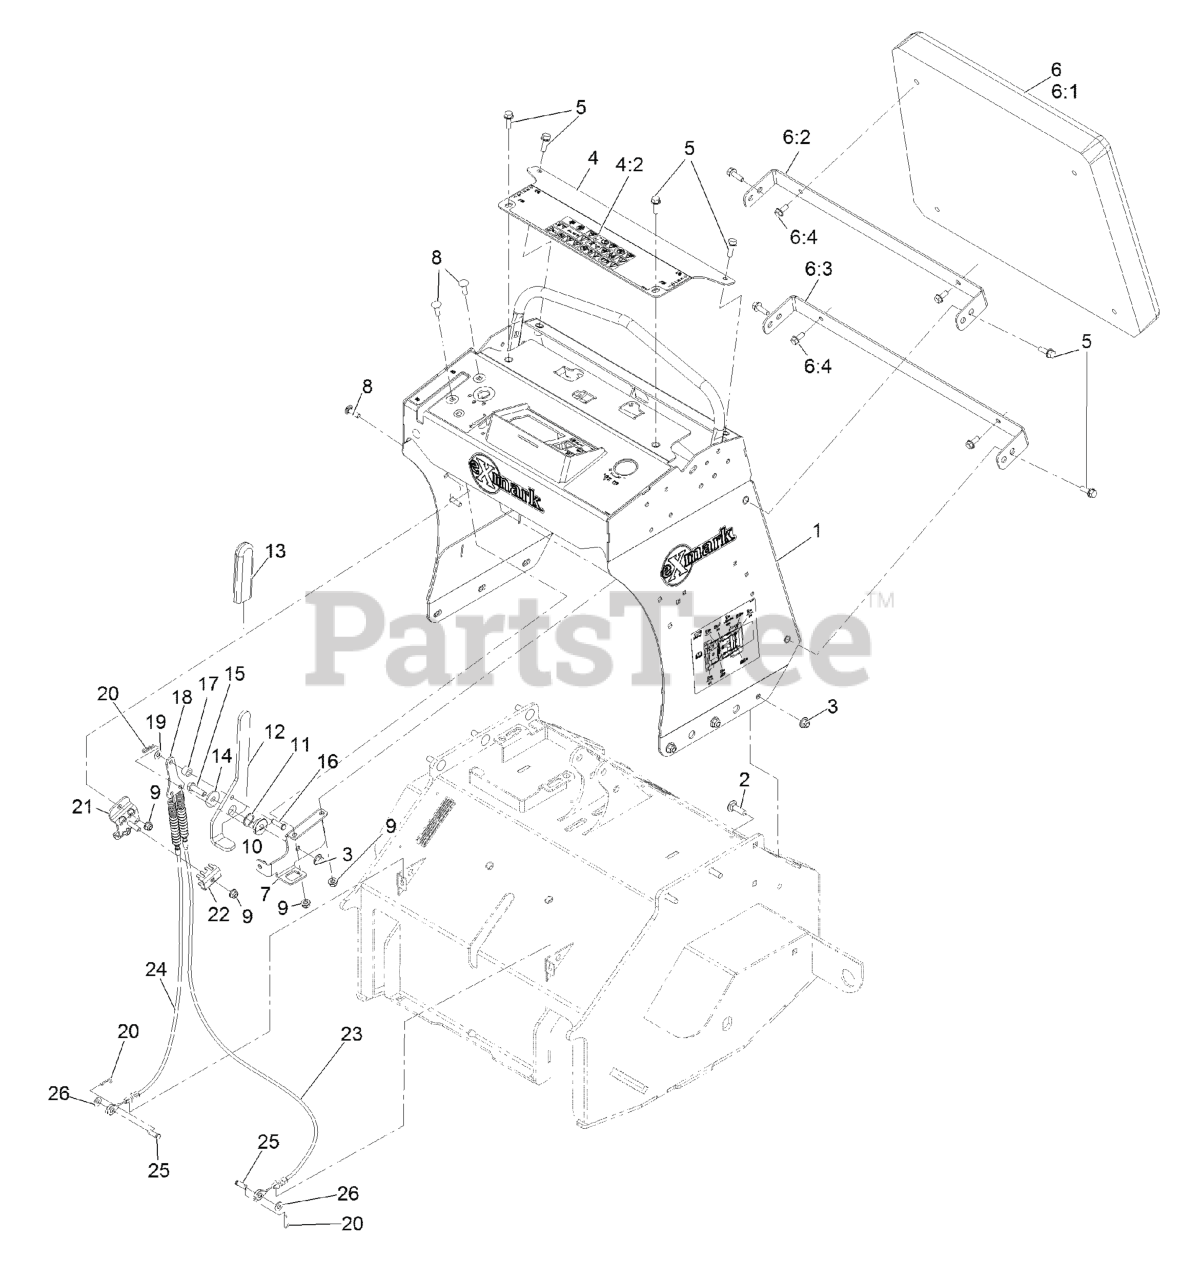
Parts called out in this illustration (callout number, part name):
1	CONTROL TOWER ASM
2	BOLT-CARR
3	NUT-HF, NI
4	CONTROL PANEL ASM
4:2	DECAL-WARNING
5	SCREW-HHF
6	Cushion ASM
6:1	CUSHION-GREY
6:2	BRACKET-PAD, UPPER
6:3	BRACKET-PAD, LOWER
6:4	SCREW-HHF
7	BRACKET-PIVOT, BRAKE
8	SCREW-CARR
9	NUT-HF, NI
10	PIVOT-FLANGE
11	WASHER-WAVE
12	HANDLE-BRAKE
13	GRIP-LEVER
14	WASHER
15	SCREW-HH
16	Pin-Yoke
17	Bushing
18	Yoke-Cable
19	SPACER-NYLON
21	Mount-Cable, Brake
22	Clamp-Cable
23	CABLE-BRAKE, LH
24	CABLE-BRAKE, RH
25	PIN-CLEVIS
26	WASHER-PLAIN
